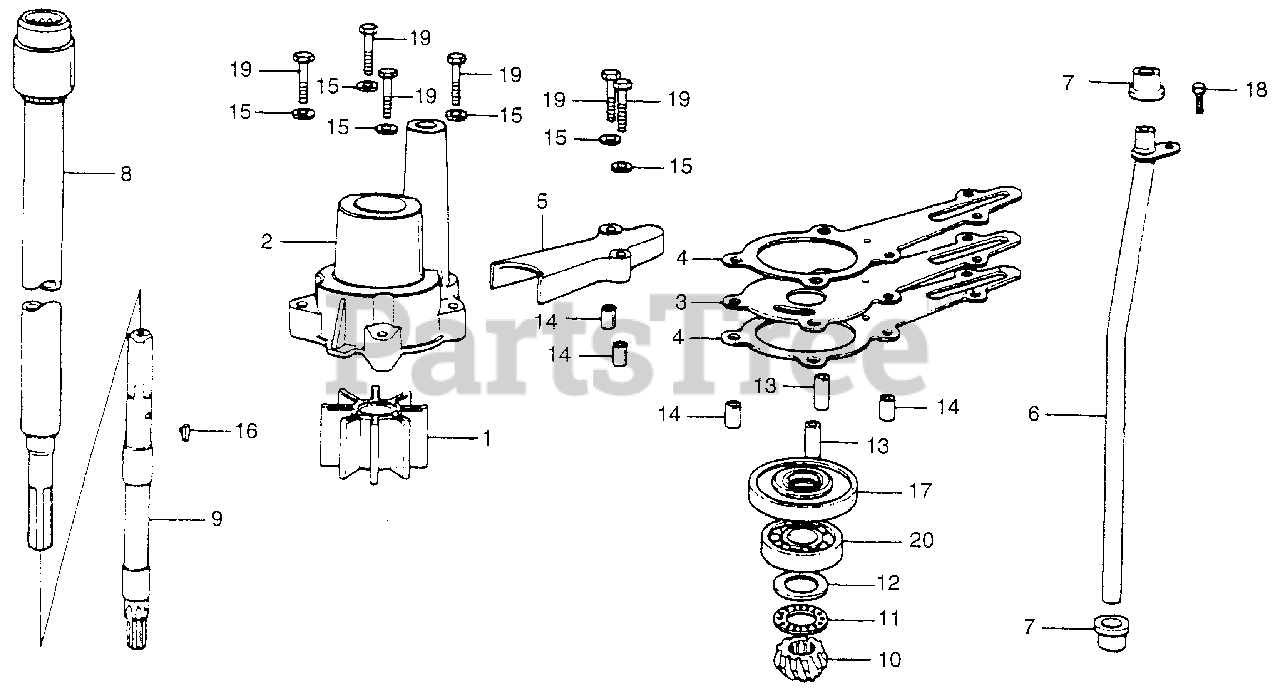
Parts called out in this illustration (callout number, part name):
1	IMPELLER, PUMP
2	HOUSING, IMPELLER
3	COVER, IMPELLER
4	GASKET, IMPELLER
5	HOLDER, IMPELLER COVER
6	TUBE, WATER (S)
6	TUBE, WATER (L) (NOT AVAILABLE)
7	RING, SEAL
8	SHAFT, VERTICAL (S)
8	SHAFT, VERTICAL (L)
9	SHAFT, PINION (NOT AVAILABLE)
10	PINION, BEVEL
11	BEARING, THRUST (15MM)
12	WASHER A, THRUST BEARING (2.00MM)
12	WASHER B, THRUST BEARING (2.05MM)
12	WASHER C, THRUST BEARING (2.10MM)
13	COLLAR A, DISTANCE
14	COLLAR B, DISTANCE
15	WASHER, PLAIN (6MM)
16	KEY, IMPELLER
17	SEAL, WATER (15MM) (NOK)
18	BOLT, HEX. (6X12)
19	BOLT, HEX. (6X28)
20	BEARING, RADIAL BALL (6302)
